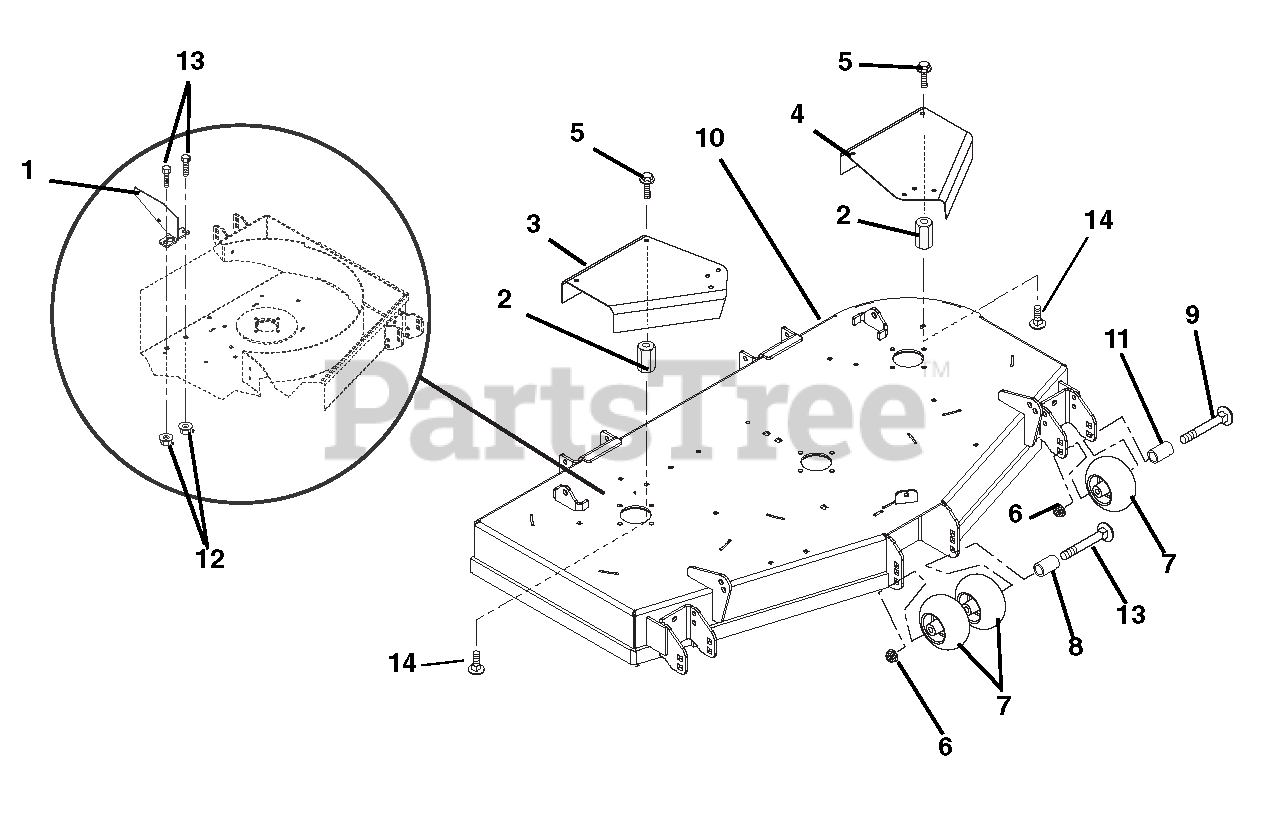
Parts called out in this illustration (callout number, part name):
1	REAR DISCH DEFLECT BFL WMT-RED
2	NUT, COUPLING .31-18 X 3.00
3	GUARD, 52" RH SPINDLE SHEAVE
3	GUARD, 60" RH SPINDLE SHEAVE
3	GUARD,66"-72"RH SPINDLE SHEAVE
4	GUARD, 44"-52" LH SPNDL SHEAVE
4	GUARD, 60" LH SPINDLE SHEAVE
4	GUARD,66"-72"LH SPINDLE SHEAVE
5	BOLT, SEMS .31-18 X .62
6	@NUT-LK-NYL-FLG .50-13 YWZC
7	ANTI-SCALP WHEEL - 5X3 CTR
8	SPACER, .510X.625X6.50
9	BLT-RDHDSQNK .50-13X5.00 GR5YZ
10	XDZ52" REAR DISCH DECK WMT-RED
10	XDZ60" REAR DISCH DECK WMT-RED
10	72"XDZ REAR DISCH DECK WMT-RED
11	SPACER, .510X.625X3.35
12	@NUT-LK-NYL-FLG .38-16 YWZC
13	@BLT-RDHDSHSQNK.38-16X1.0 G5YZ
14	BLT,RDHDSQNK .31-18X.75 LOCTIT
